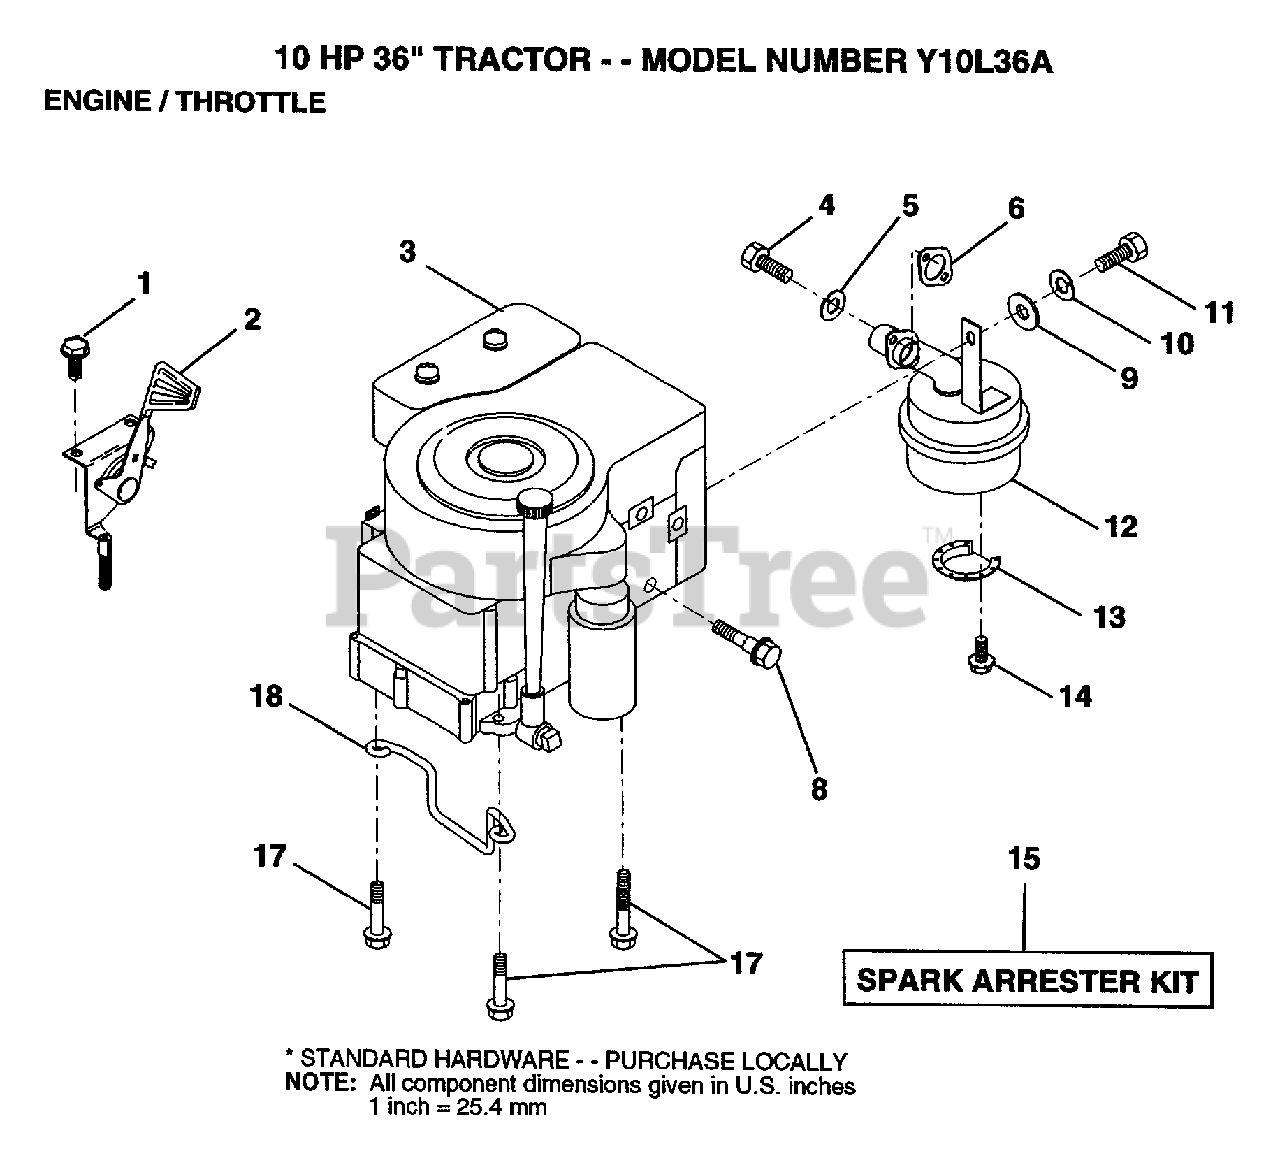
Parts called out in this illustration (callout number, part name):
1	SCREW
2	THROTTLE CONTROL
4	SCREW
5	LOCKWASHER
8	BOLT T
10	LOCKWASHER
12	MUFFLER
13	DEFLECTOR.222573
17	SCREW LT
18	"KEEPER,DR BELT GR"
